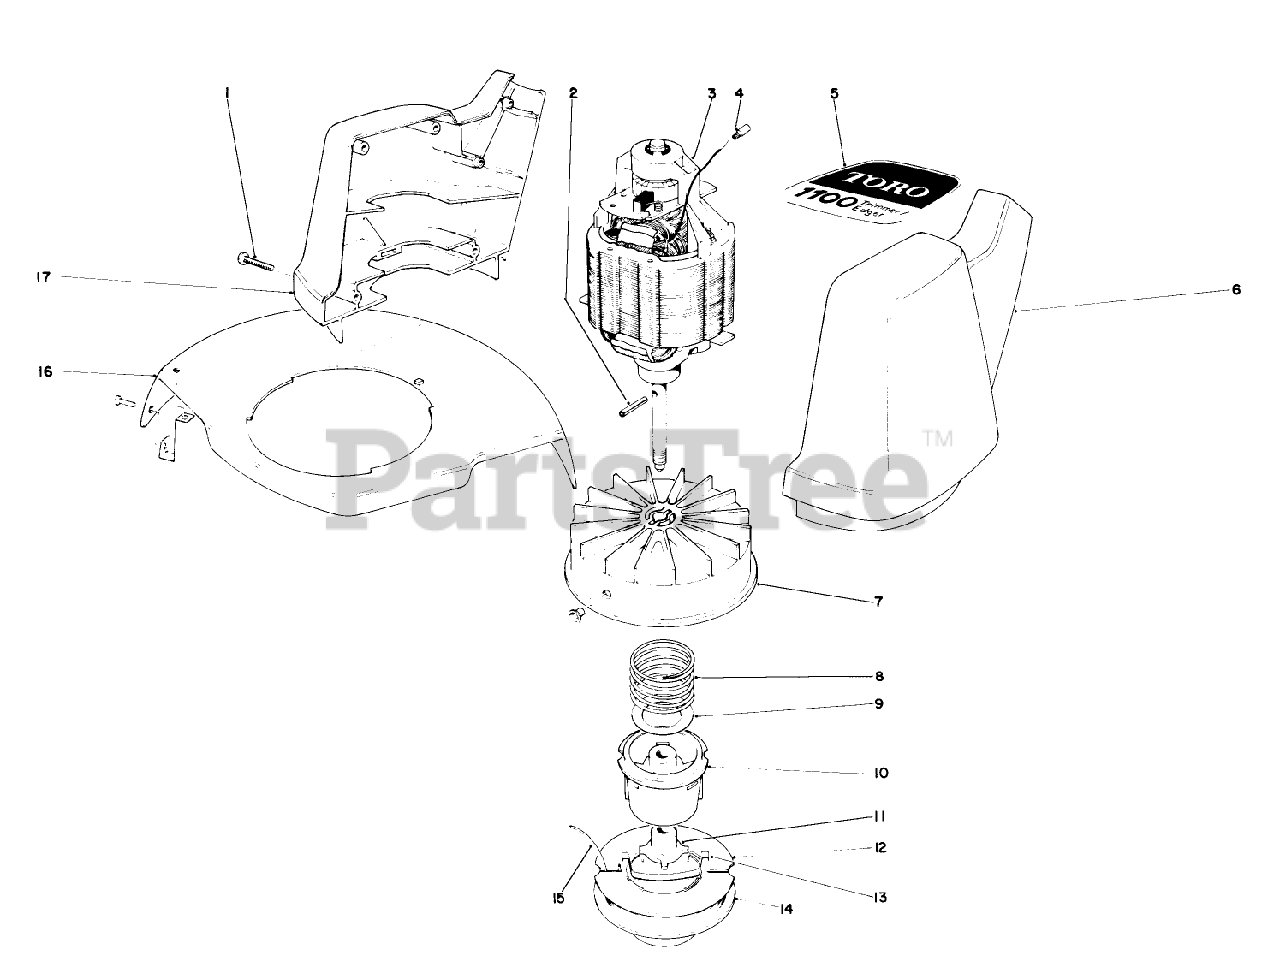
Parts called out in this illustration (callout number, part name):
1	SCREW-PPH
2	COIL PIN
3	Motor
4	CONNECTOR WIRE JOINT
5	Toro 1100 Decal
6	Left Motor Housing
7	DRUM W/EYELET
8	SPRING COMPRESSION
9	WASHER-FLAT
10	SPOOL CORE
11	Driver
12	Empty SPooI
13	SADDLE-SPOOL CAP
14	Prewound Spool
15	50-Coil.065" Cutting Line
16	Shield with Cut Off Blade
17	Right Motor Housing
